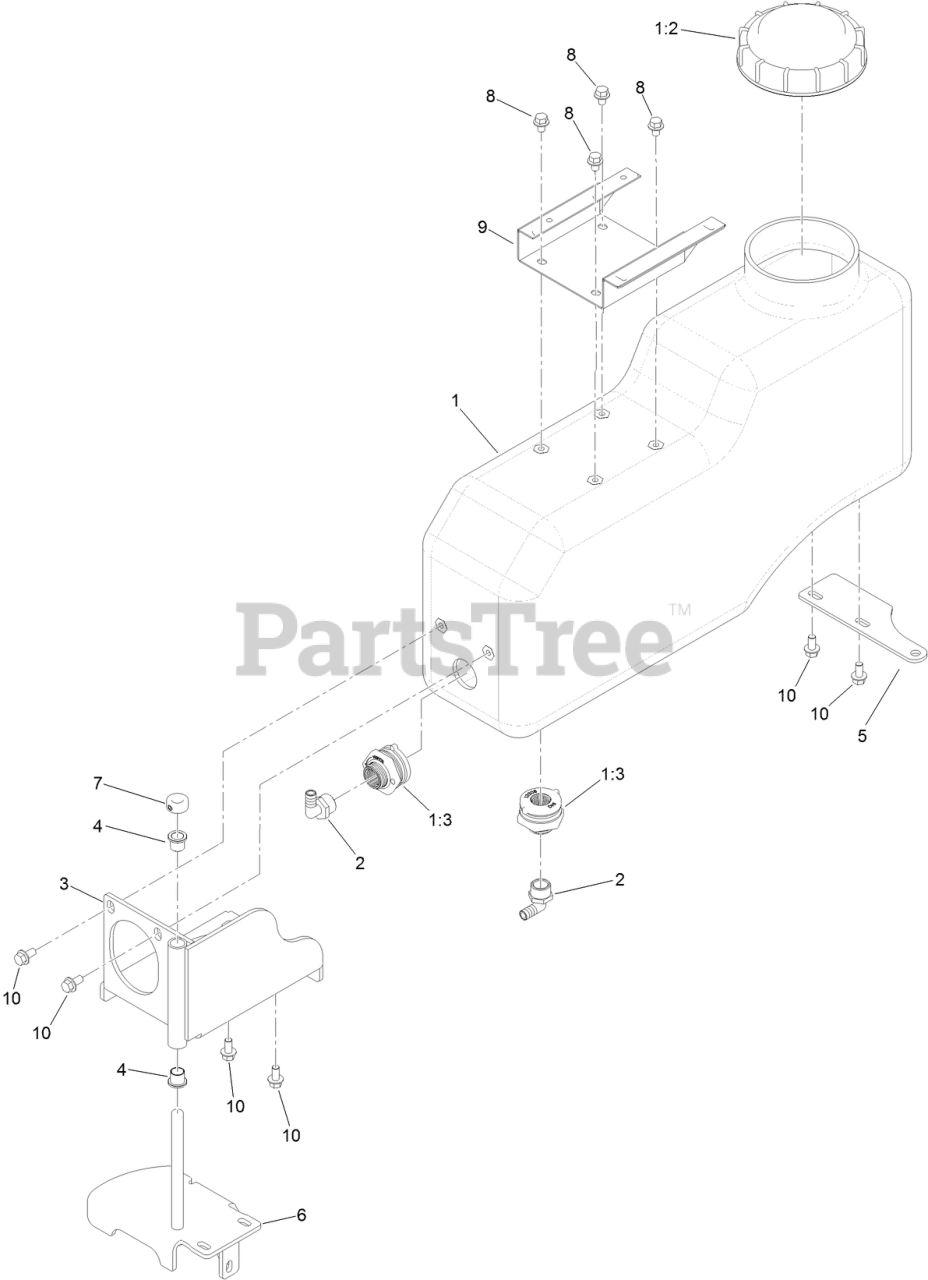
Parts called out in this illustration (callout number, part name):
1	ASM-TANK, RT
1:2	CAP-TANK, SPRAY
1:3	FITTING-BULKHEAD
2	FITTING-ELBOW, 90
3	WLD, WING, TANK, BOTTOM, R, JR36
4	BUSHING-FLANGE
5	PLATE, PIVOT LOCK, TANK, JR36
6	WLD, WING, TANK, BOTTOM, R, JR36
7	5/8 SHAFT COLLAR
8	SCREW-HHF
9	PLATFORM-VALVE, LIQUID
10	SCREW-HHF
